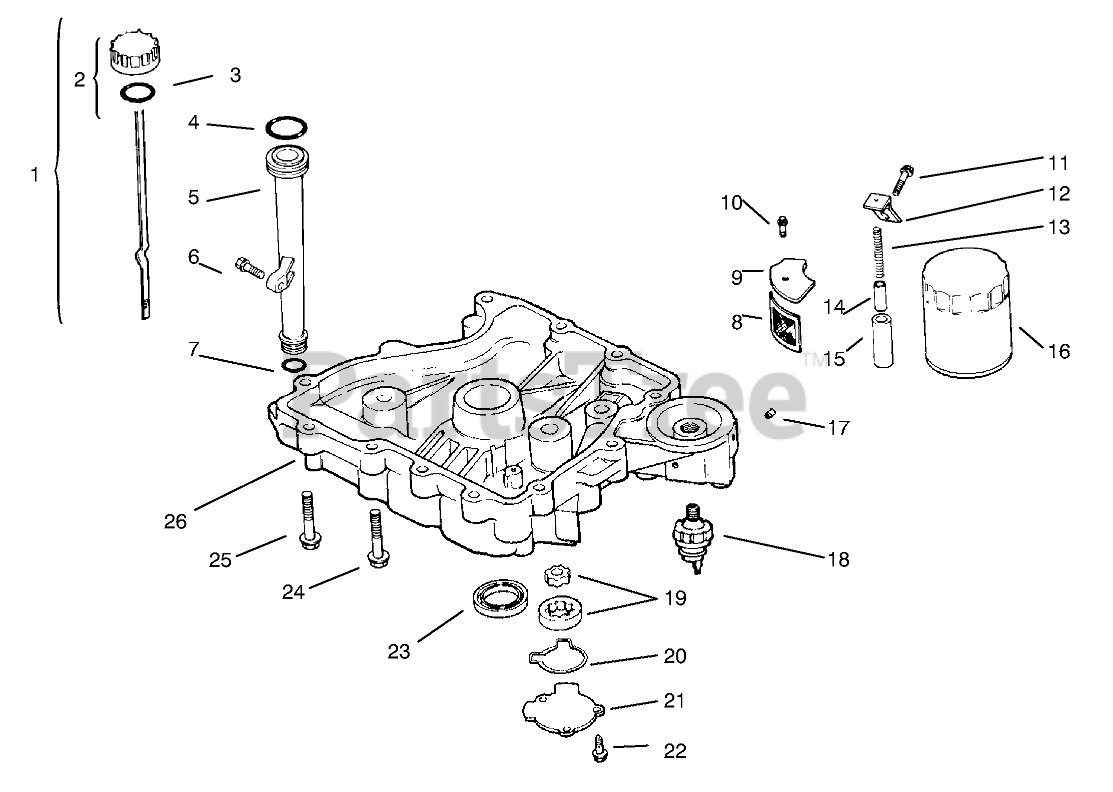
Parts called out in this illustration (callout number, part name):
1	Dipstick INC 2-3
2	Kit-Oil Fill Cap
3	"O"Ring
4	"O"Ring
5	Tube-Oil Fill
7	"O"Ring
8	Screen-Oil Pickup
9	Cover-Oil Screen
10	Screw-HF
11	Screw
12	Bracket-Oil Pump Relief
13	Spring-Oil Relief Valve
14	Piston-Oil Relief Valve
15	Body-Oil Relief Valve
16	Filter-Oil
17	Plug
18	Switch, pressure
19	Pump-Oil
20	"O"Ring-Pump Cover
21	Cover-Oil Pump
22	Screw-HF
23	Seal-Crankshaft
24	Screw
25	Screw
26	Pan-Oil
